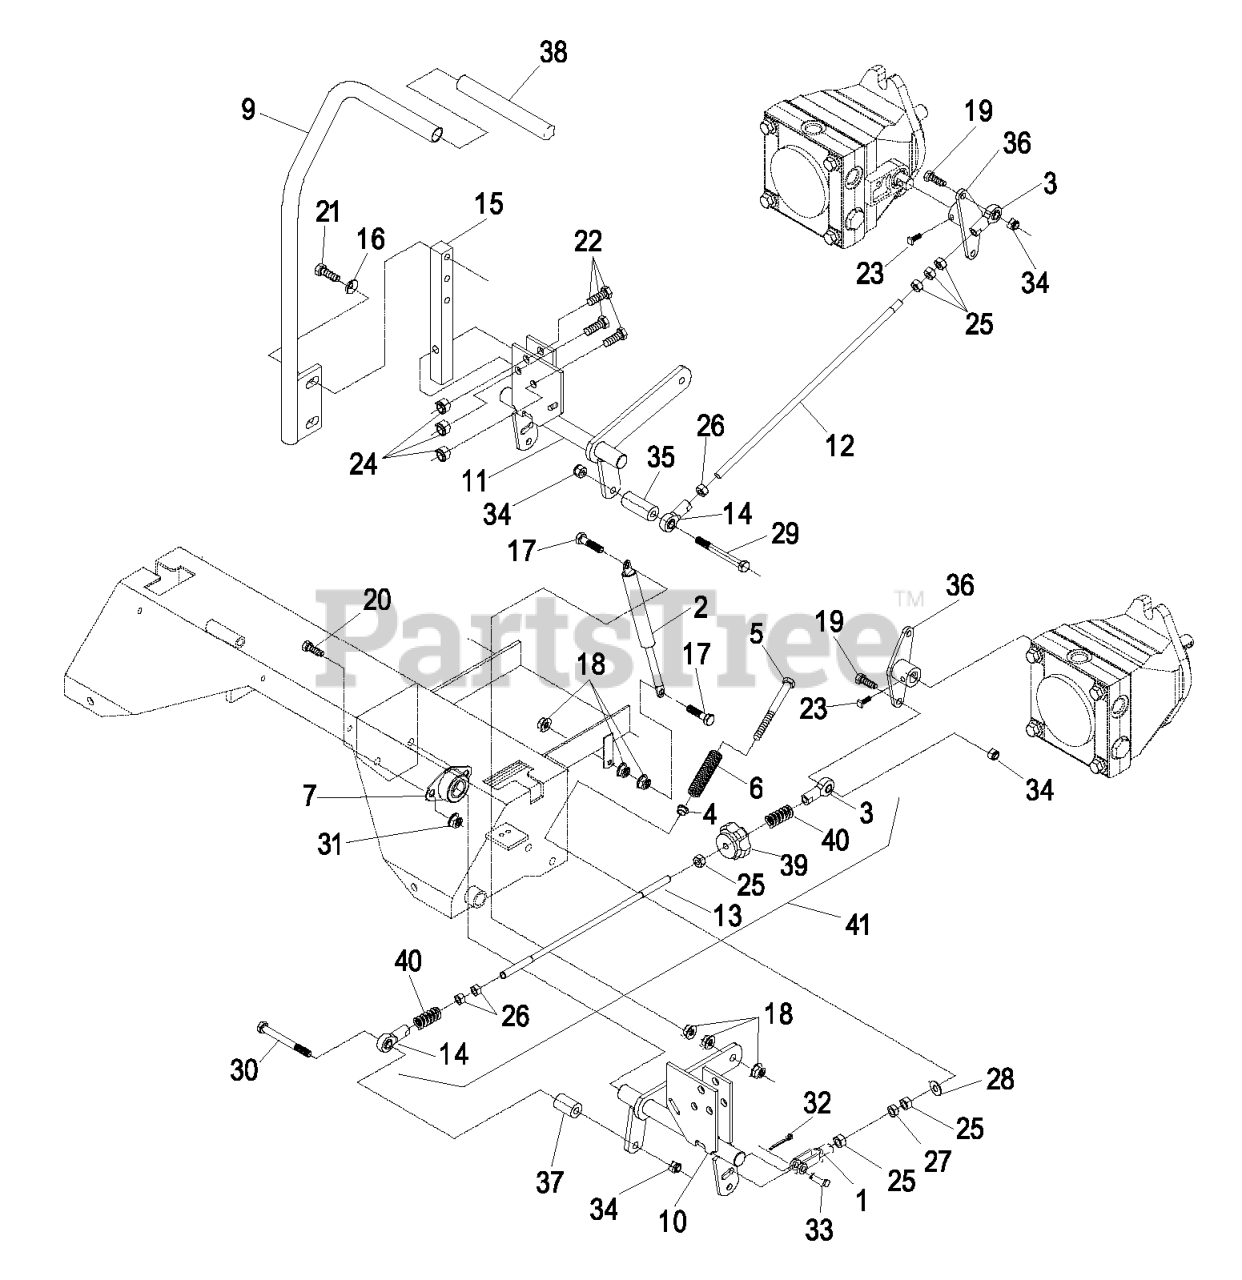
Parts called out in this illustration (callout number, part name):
1	YOKE-ADJUSTABLE
3	BALLJOINT-RH
4	BUSHING-FLANGED
5	BOLT-RETURN, NEUTRAL
6	SPRING-RETURN, NEUTRAL
7	BEARING-FLANGE, SIDE
9	RH LEVER ASM
13	LINK,TRACKING ROD XP
14	BALLJOINT-LH
15	ARM-SHAFT, CONTROL
16	WASHER-BELLEVILLE
17	SCREW-HH
19	SCREW-HH
20	SCREW-HH
21	SCREW-HH
22	SCREW-HH
23	SCREW-SET
24	NUT-LOCK, NI
25	NUT-HEX
27	NUT-JAM
28	WASHER-FLAT
29	SCREW-HH
30	SCREW-HH
31	NUT-HHF, WHIZ
32	PIN-COTTER
33	PIN-CLEVIS
34	NUT-LOCK, NI
36	ARM-CONTROL, HYDRO
37	SPACER-HYDRO CONTROL, LH
38	GRIP-CONTROL, MOTION
39	KNOB-TRACKING
40	SPRING-COMPRESSION
41	TRACKING ROD ASM
